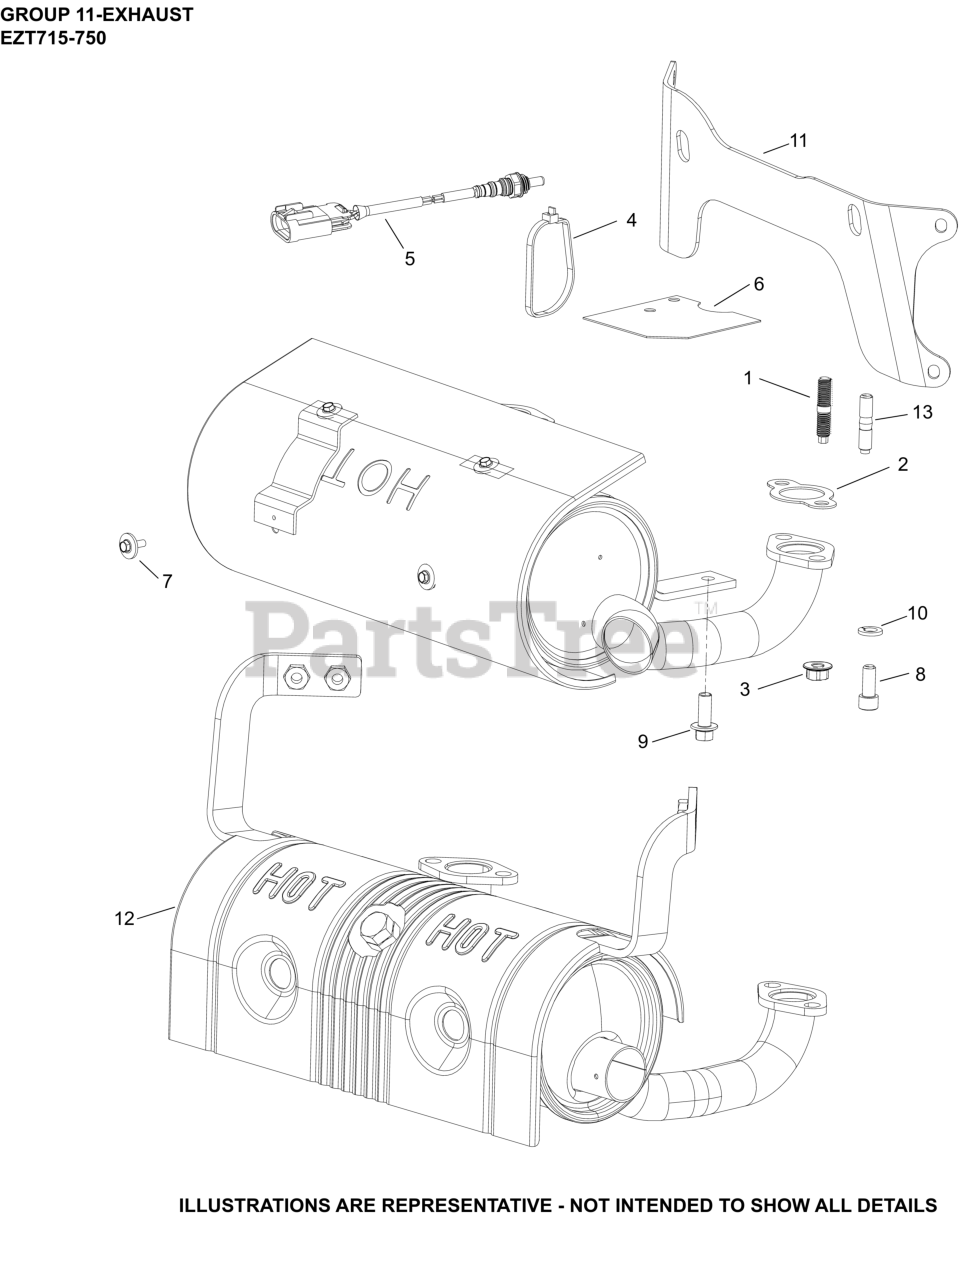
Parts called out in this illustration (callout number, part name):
3	NUT, HEX FLANGE LOCK (M8)
5	SENSOR, OXYGEN (M18 x 1.5 THREADS)
13	STUD, METRIC EXHAUST
NI	BRACKET, MAIN SUPPORT
NI	GASKET, EXHAUST MANIFOLD
